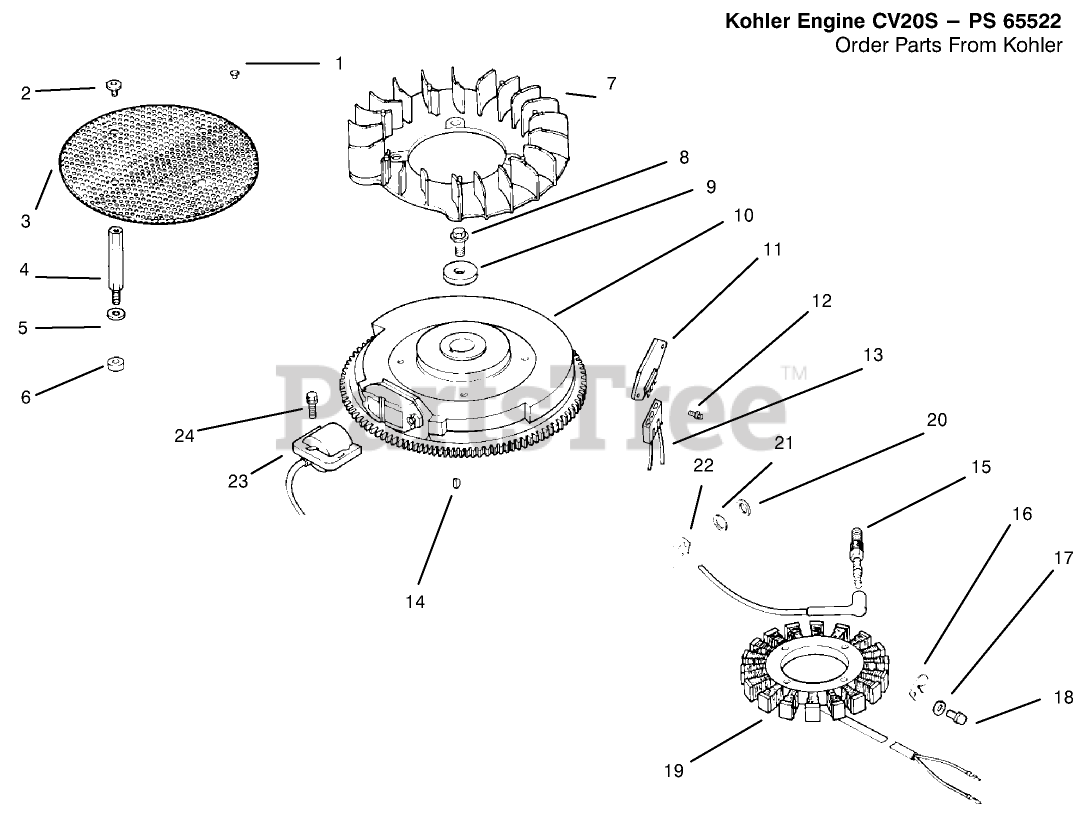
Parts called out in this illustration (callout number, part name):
1	Screw-Set
2	Screw
3	Screen-Grass
4	Stud
5	Washer
6	Spacer
7	Fan
8	Screw
9	Washer
10	Flywheel
11	Rectifier-Regulator
12	Screw
13	Connector
14	Key
15	Plug-Spark
16	Clip
17	Washer
18	Screw
19	Stator-15 Amp
20	Washer
21	Washer
22	Clip
23	Module-Ignition
24	Screw
